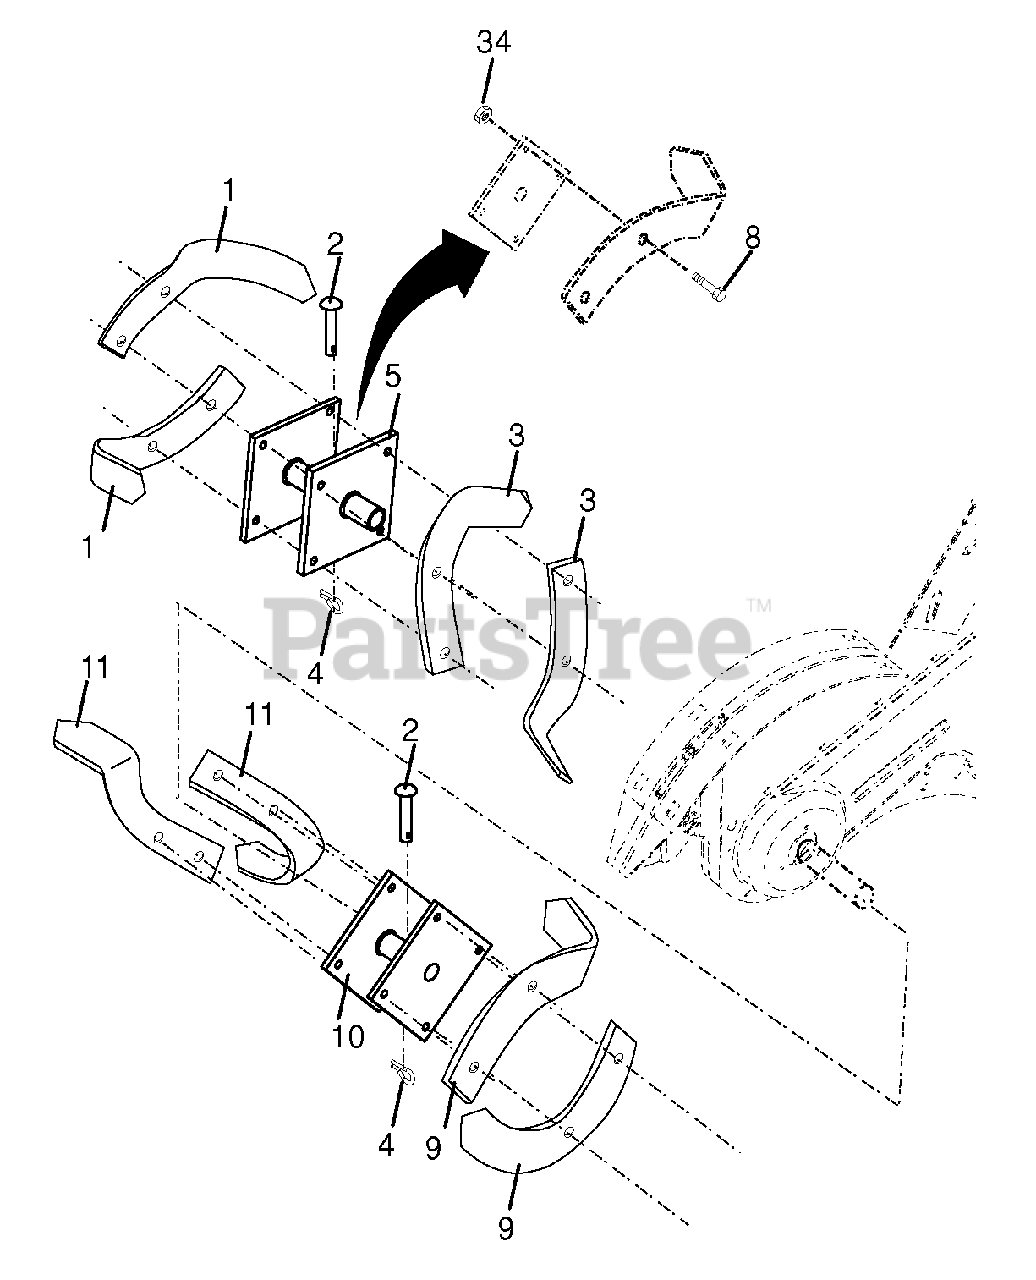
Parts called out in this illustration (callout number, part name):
1	TINE TI
2	CLEVIS PIN
3	TINE.LH.12"
4	SPRING RETAINER
5	HUB.&.PLATE.LH.TILLER.BLACK
8	BOLT.HEX.001X20.37-24X1.ZINC
9	TINE TI
11	TINE.RH.12"(72R)
34	NUT CROWNLOCK 3/8-24
